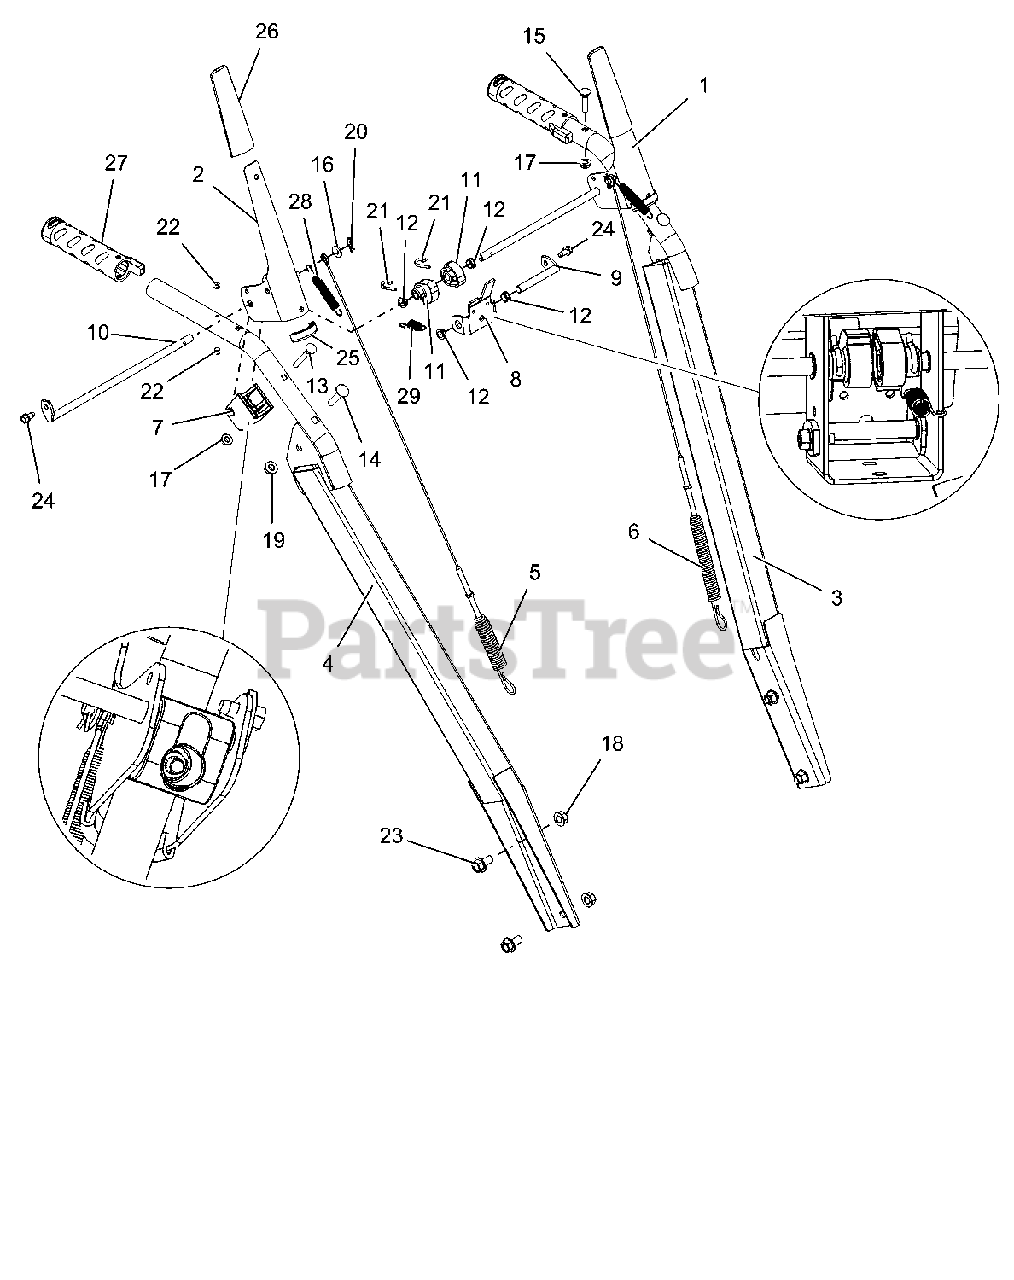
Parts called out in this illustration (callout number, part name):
1	LEVER, CLUTCH-LH
2	LEVER, CLUTCH-RH
3	HANDLEBAR, HEAVYDUTY-PRO LH
4	HANDLEBAR, HEAVYDUTY-PRO-RH
5	CABLE, AUGER (DELUXE & PRO)
6	CABLE, UPPER TRACTION
7	BLOCK, CLUTCH PADDLE
8	BRACKET, INTERLOCK ARM
9	ROD, PIVOT - INTERLOCK
10	ROD, PADDLE MOUNT - PRO
11	CAM, INTERLOCK
12	BUSHING, POLYLINER-.38 SNAPIN
13	BLT-RDHDXLSQNK .25-20X2.0 G5YZ
14	@BLT-RDHDSQNK .31-18X1.50 G5YZ
15	BLT-RDHDXLSQNK.25-20X1.25 G5ZC
16	@WSHR-FL-STL.281X.62X.065 YWZC
17	@NUT-LK-CTR-FLG .25-20 YWZC
18	@NUT-LK-TOP-FLG .38-16 YWZC
19	@NUT-LK-TOP-FLG .31-18 YWZC
20	PIN-HAIR INT .06X.18X.77
21	PIN, SPRING CLIP
22	RVT-POP #43 .125X.313 STL ZINC
23	BLT-SERHFWH .38-16X.75 YWZC
24	SCR-TAP .25-20X.50 HWH TR YWZ
25	EDGING, CLUTCH PADDLE - 2.00"
26	SLEEVE, CLUTCH PADDLE-GRAY
27	GRIP,HEATED HANDLE-GRAY
28	SPRING, EXTENSION
29	SPRING-EXT .047X.438X1.45
